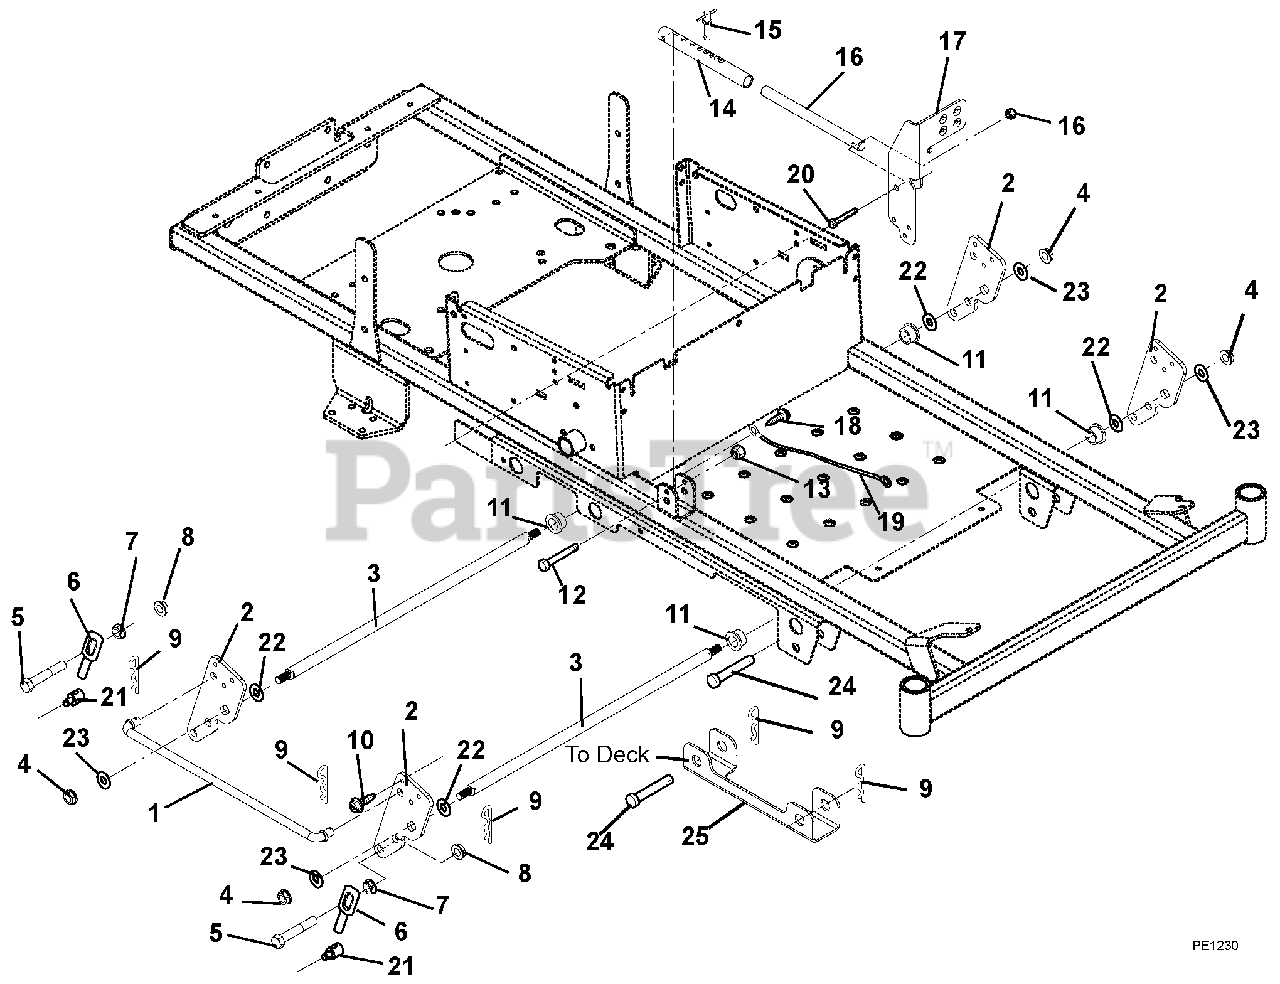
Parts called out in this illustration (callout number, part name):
1	ROD,LIFT
2	LIFT ARM
3	SHAFT, LIFT
4	NUT-HEX .250-28 YWZC
5	BLT-HEX .50-13X2.75 YZ GR8
6	DECK LINK
7	NUT-SPNLK-FLG .50-13 YWZC
8	@NUT-LK-NYL-FLG .50-13 YWZC
9	PIN, HAIR, EXT - #16 YWZC
10	@SCR-TAP .31-18X.50 HWH TR YWZ
11	BSHG-FLG .750X1.000X.625X1.250
12	@BLT-HEX .38-16X2.00 GR5 YWZC
13	@NUT-LK-NYL-FLG .38-16 YWZC
14	TUBE,LIFT STOP
15	PIN, SPRING BALL .375OD X 1.50
16	ROD,LIFT
17	PEDAL,FOOT LIFT
18	@SCR-TAP .25-20X.50 HWH TR YWZ
19	CBL,HOOD
20	@BLT-HEX .38-16X2.50 GR5 YWZC
21	TRUNNION-.50
22	WSHR-FL-STL.755X1.375X.062YWZC
23	WSHR-FL-STL .515X1.625X.250 YZ
24	PIN-CLEV .494X2.50 BRIGHT ZINC
25	CHAANEL, DECK LIFT
